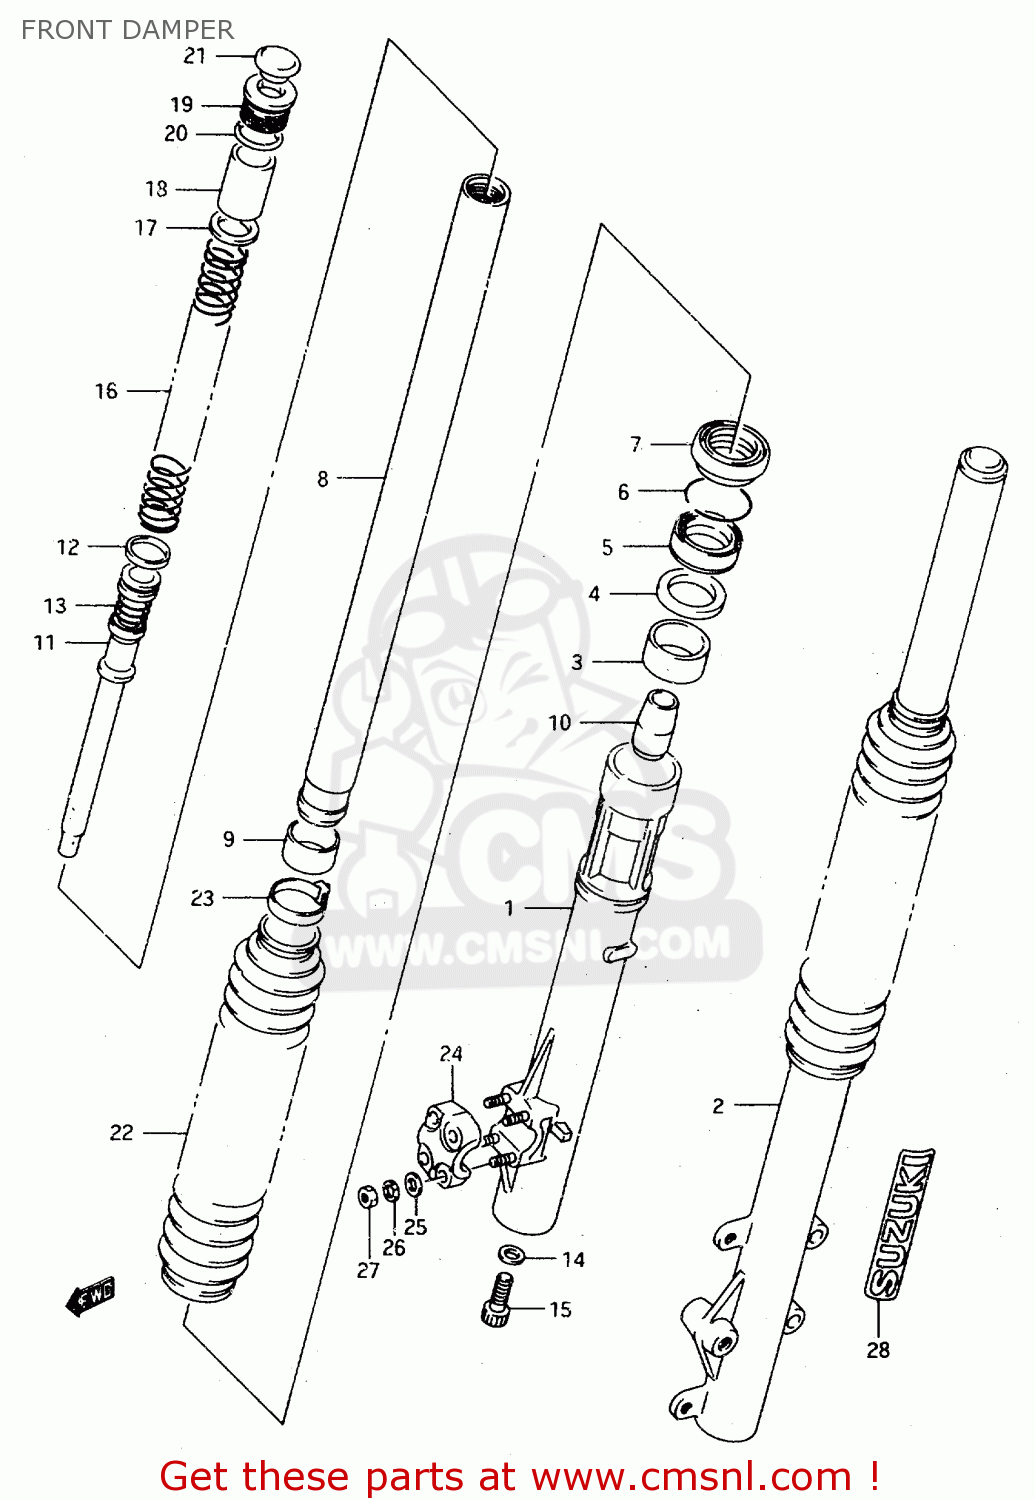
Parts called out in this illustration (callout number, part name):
1	TUBE, OUTER RH
2	TUBE,OUTER,L
3	BUSH,GUIDE
4	SPACER,SEAL
5	SEAL,OIL
6	CIRCLIP,FORK OIL SEAL
7	SEAL,DUST
8	TUBE,INNER
9	BUSH,SLIDE
10	PIECE,OIL LOCK
11	CYLINDER
12	RING,PISTON
13	SPRING,REBOUND
14	GASKET (NAS)
15	BOLT(8X27)
16	SPRING
17	JOINT,SPRING
18	COLLAR,SPRING(32.9X34X50)
19	BOLT, FORK
20	O RING
21	CAP,FORK
22	BOOT
23	BAND,BOOT
24	HOLDER, AXLE RH
25	WASHER
26	WASHER,LOCK
27	NUT
28	EMBLEM, SUZUKI
